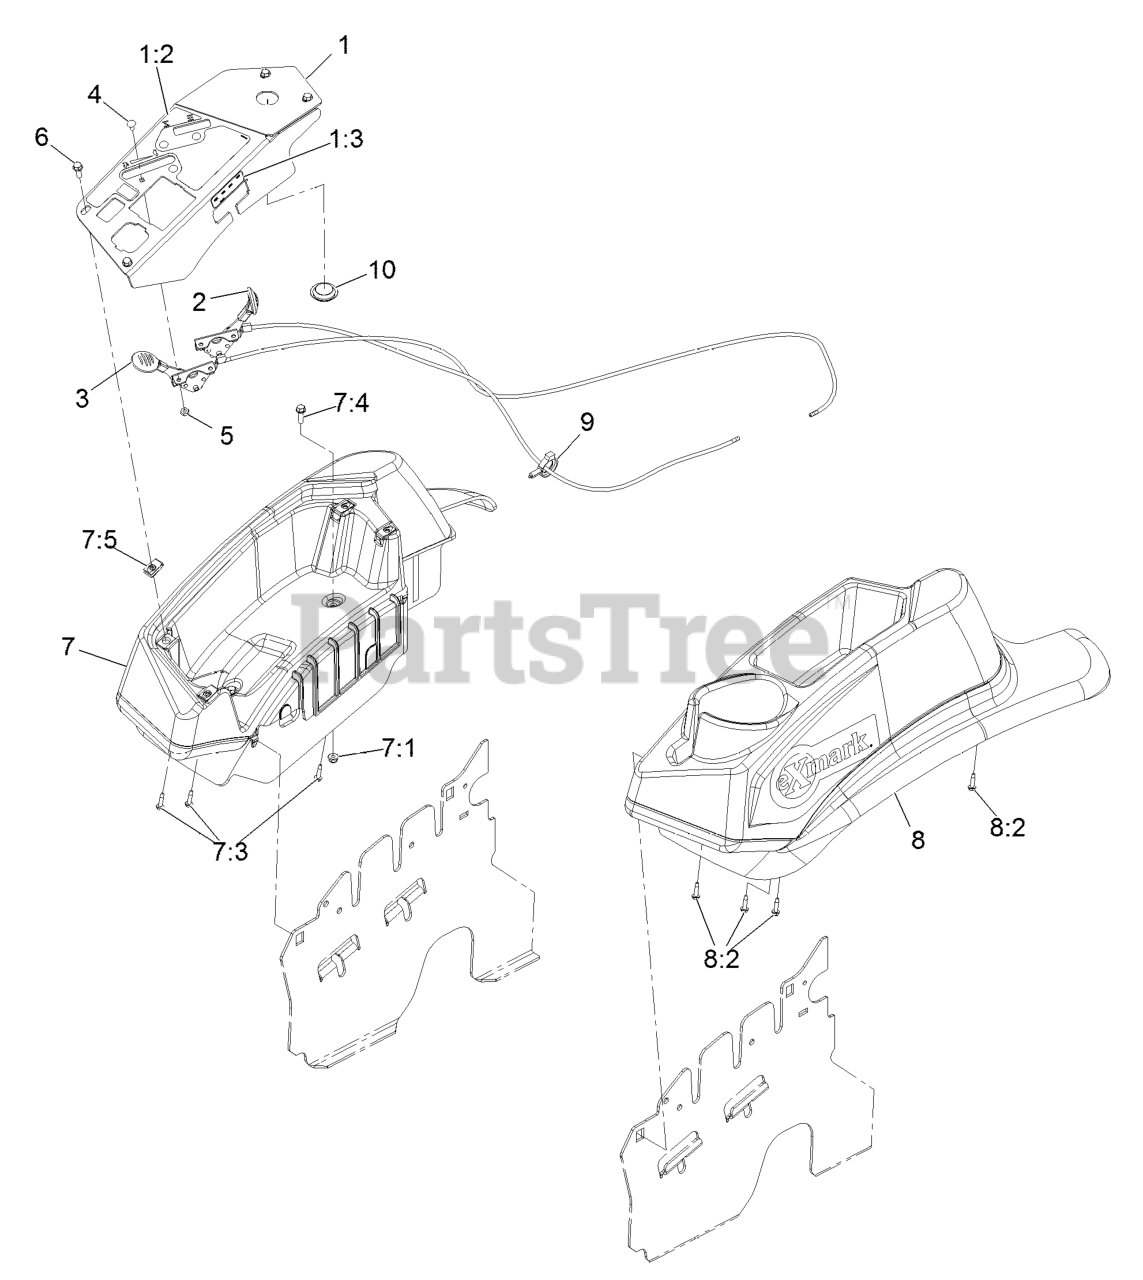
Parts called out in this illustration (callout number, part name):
1	CONSOLE,PANEL W/DECAL
1:2	DECAL-CONTROL PANEL
1:3	DECAL-FUSE
2	ASM, CHOKE CABLE
3	ASM,THROTTLE CABLE
4	BOLT-CARR
5	NUT-LOCK, NI
6	SCREW-HWH
7	CONSOLE,RH NARROW ASM
7:3	SCREW,THD FORM,HWH
7:4	SCREW-HWH
7:5	Nut-Retainer-Panel 1/4-20
8	CONSOLE.LH NARROW ASM
8:2	SCREW,THD FORM,HWH
9	CLAMP-HOSE
10	PLUG-PLASTIC
